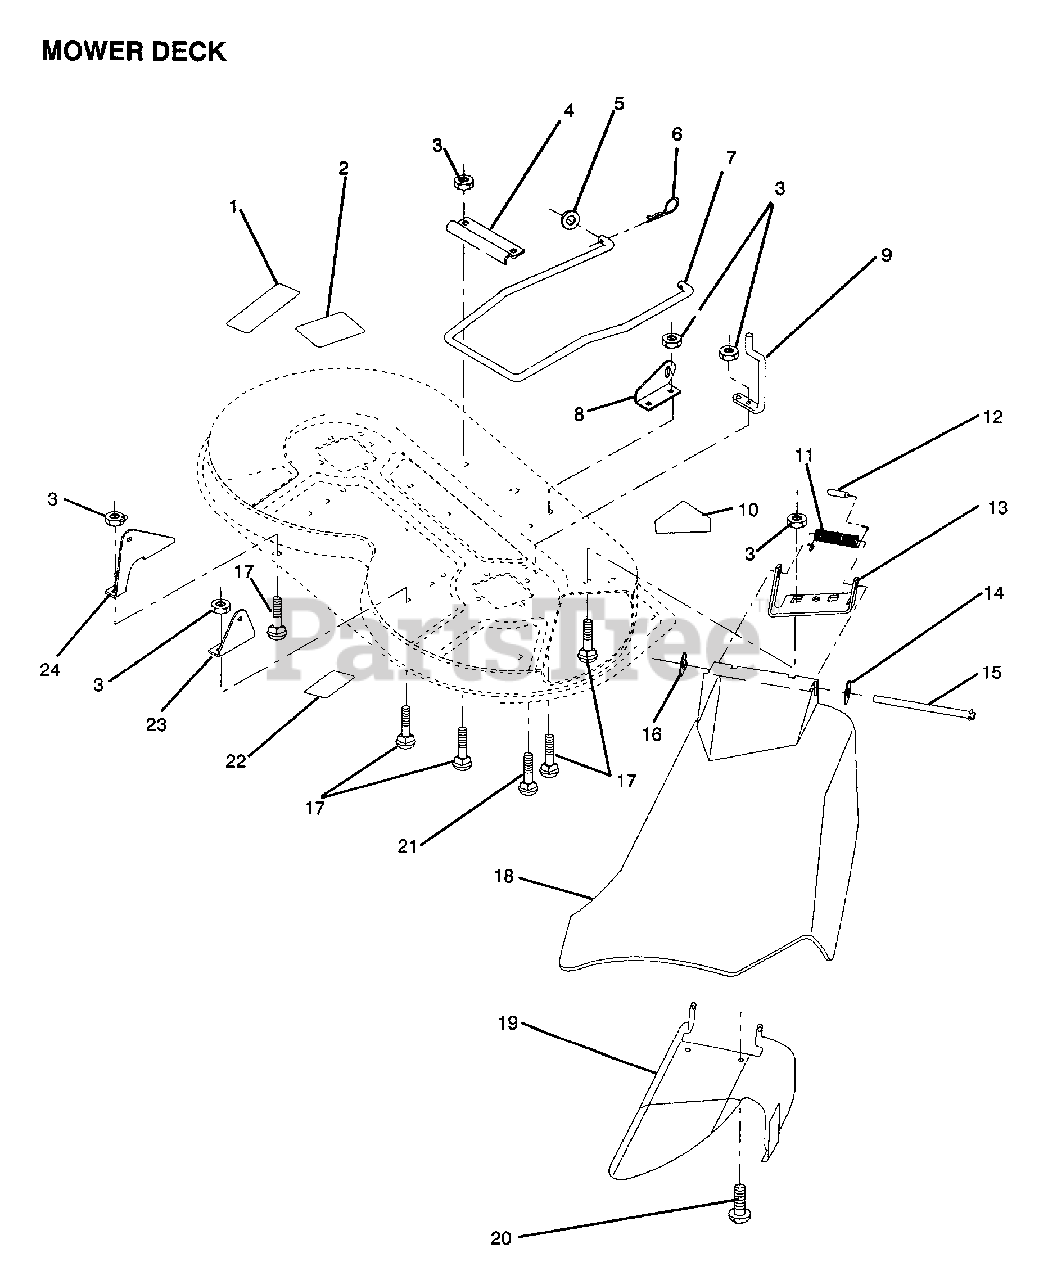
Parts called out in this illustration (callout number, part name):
1	DECAL YT
2	DECAL.LT
4	"BRKT,STAB LINK"
6	RETAINER.SPRING
7	STABILIZER MOWER
8	"BRKT,FRT LIFT RH"
9	"GUIDE,FRT MAN RH"
10	DECAL WARNING
11	SPRING TORSION
12	CAP-SLEEVE LT
14	WASHER
15	HINGE ROD
16	NUT PUSH M
17	BOLT
19	DEFL SUPT ASS'Y
20	SCREW PAN HD
21	BOLT
22	DECAL WARNING
23	"BRKT,REAR LIFT RH"
24	"BRKT,REAR LIFT LH"
